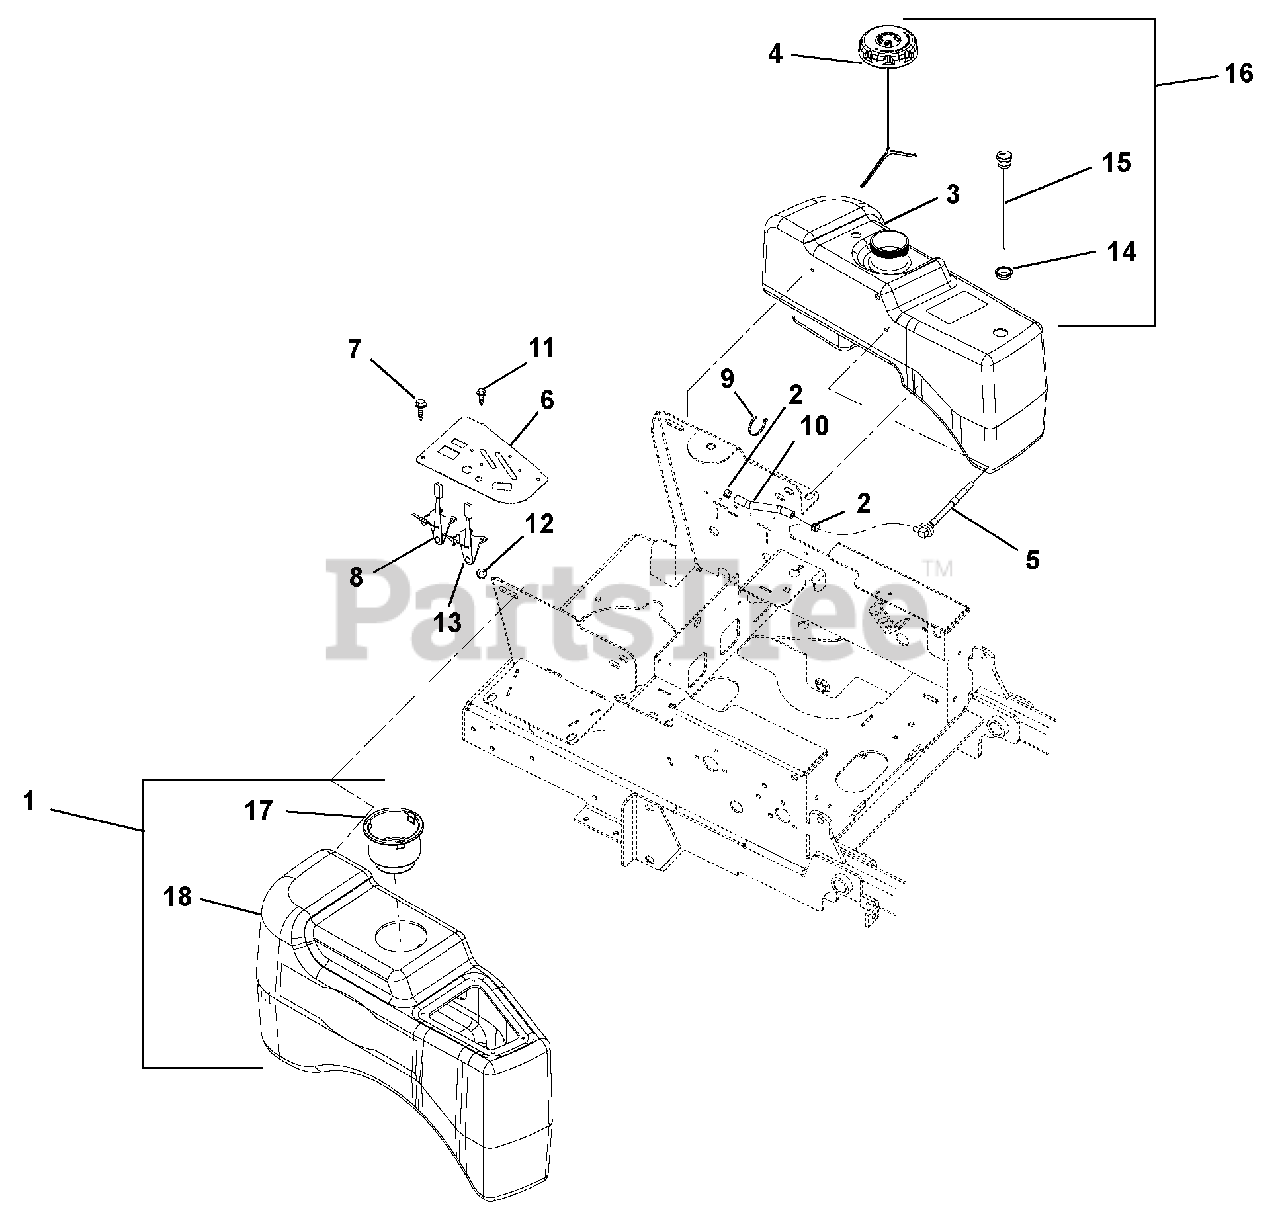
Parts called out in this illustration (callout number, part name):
1	ASM, FENDER W/CUPHOLDER
2	CLAMP, FUEL LINE
3	TANK, LH FUEL
4	CAP, FUEL VENTIN AUTOLOCK
5	ASM, FUEL PICK-UP SML/MED TANK
6	INSTRUMENT PANEL - BLK
7	SCR-PLASTITE .25-10X.75, YWZC
8	CABLE, CONTROL
9	CABLE TIE LG 5-1/2
10	HOSE, .25 LOW-PERM BULK GAS
11	@SCR-MCH 10-24X.50 HWH YWZC
12	@NUT-LK-NYL 10-24 W/INSRT YWZC
13	CABLE, THROTTLE
14	GROMMET, FUEL GAGE
15	GAUGE, REMOTE FUEL 10.0"
16	HD, FUEL TANK ASSEMBLY
17	CUPHOLDER, SNAP-IN 3.75OD
18	FENDER, RH
